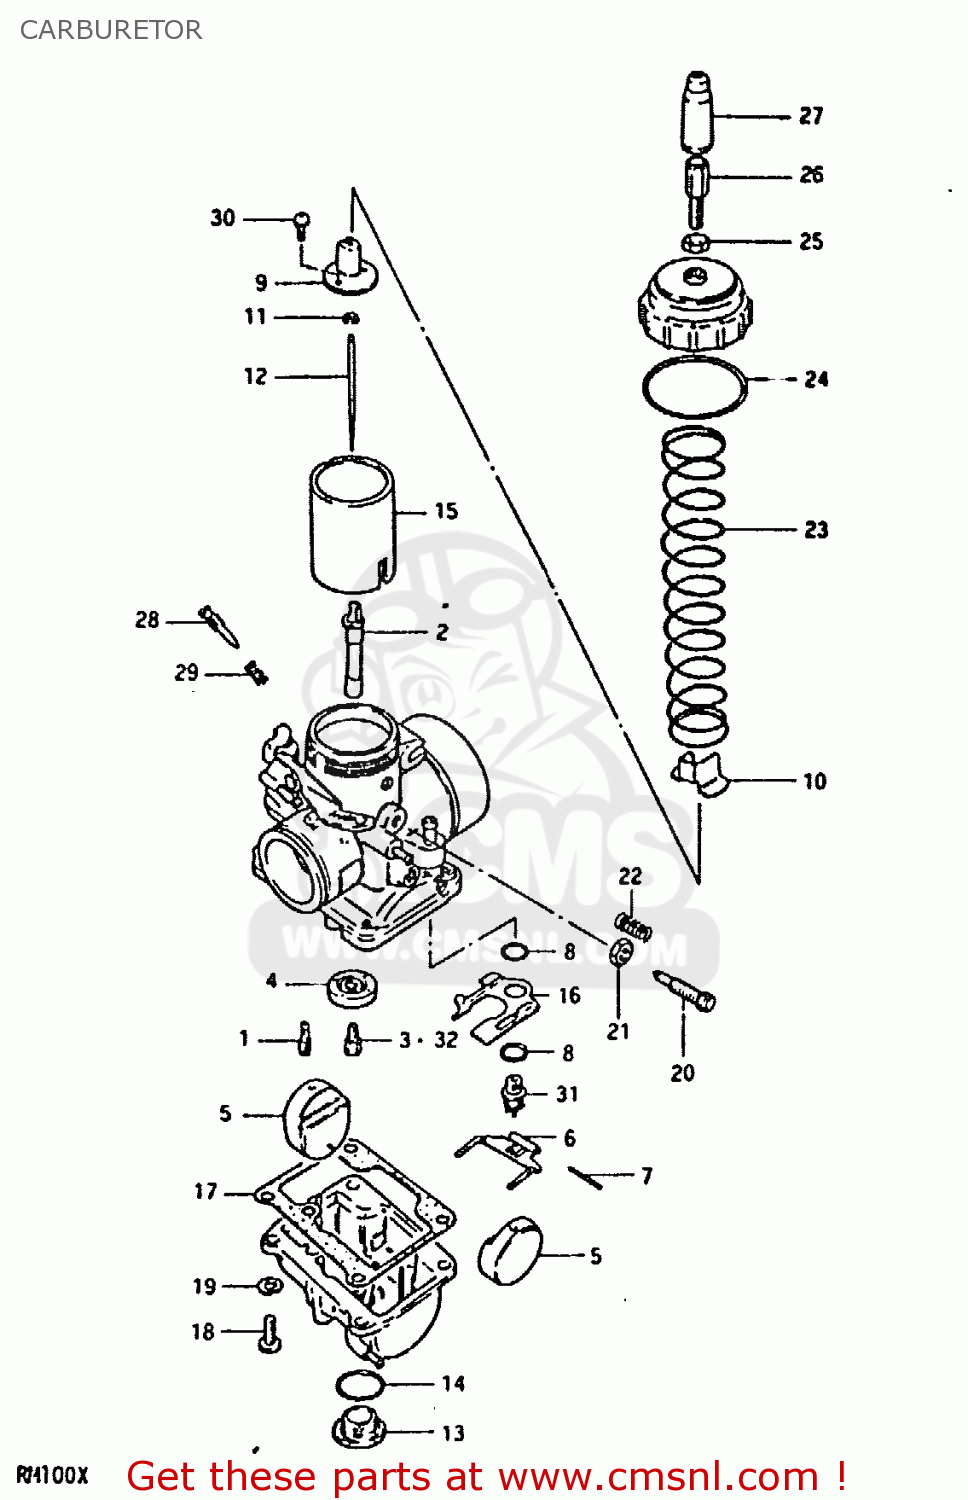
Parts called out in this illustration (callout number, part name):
1	JET
2	JET,NEEDLE
3	JET
4	RING,MAIN JET FIXING
5	FLOAT
6	ARM,FLOAT
7	PIN,FLOAT
8	GASKET,MAIN JET HOLDER (NAS)
9	CONNECTOR
10	COVER,HOLDER
11	CLIP
12	NEEDLE JET
13	PLUG
14	GASKET,DRAIN PLUG
15	VALVE,THROTTLE
16	PLATE
17	GASKET,FLOAT CAHMBER (NAS)
18	SCREW
19	LOCK WASHER
20	ADJUSTER
21	NUT
22	SPRING,THROTTLE SCREW
23	SPRING,THROTTLE VALVE RETURN
24	O-RING,MIXING CHAMBER
25	NUT
26	ADJUSTER,CABLE
27	CAP
28	SCREW,PILOT AIR
29	SPRING
30	SCREW
31	VALVE ASSY,NEEDLE
32	JET
